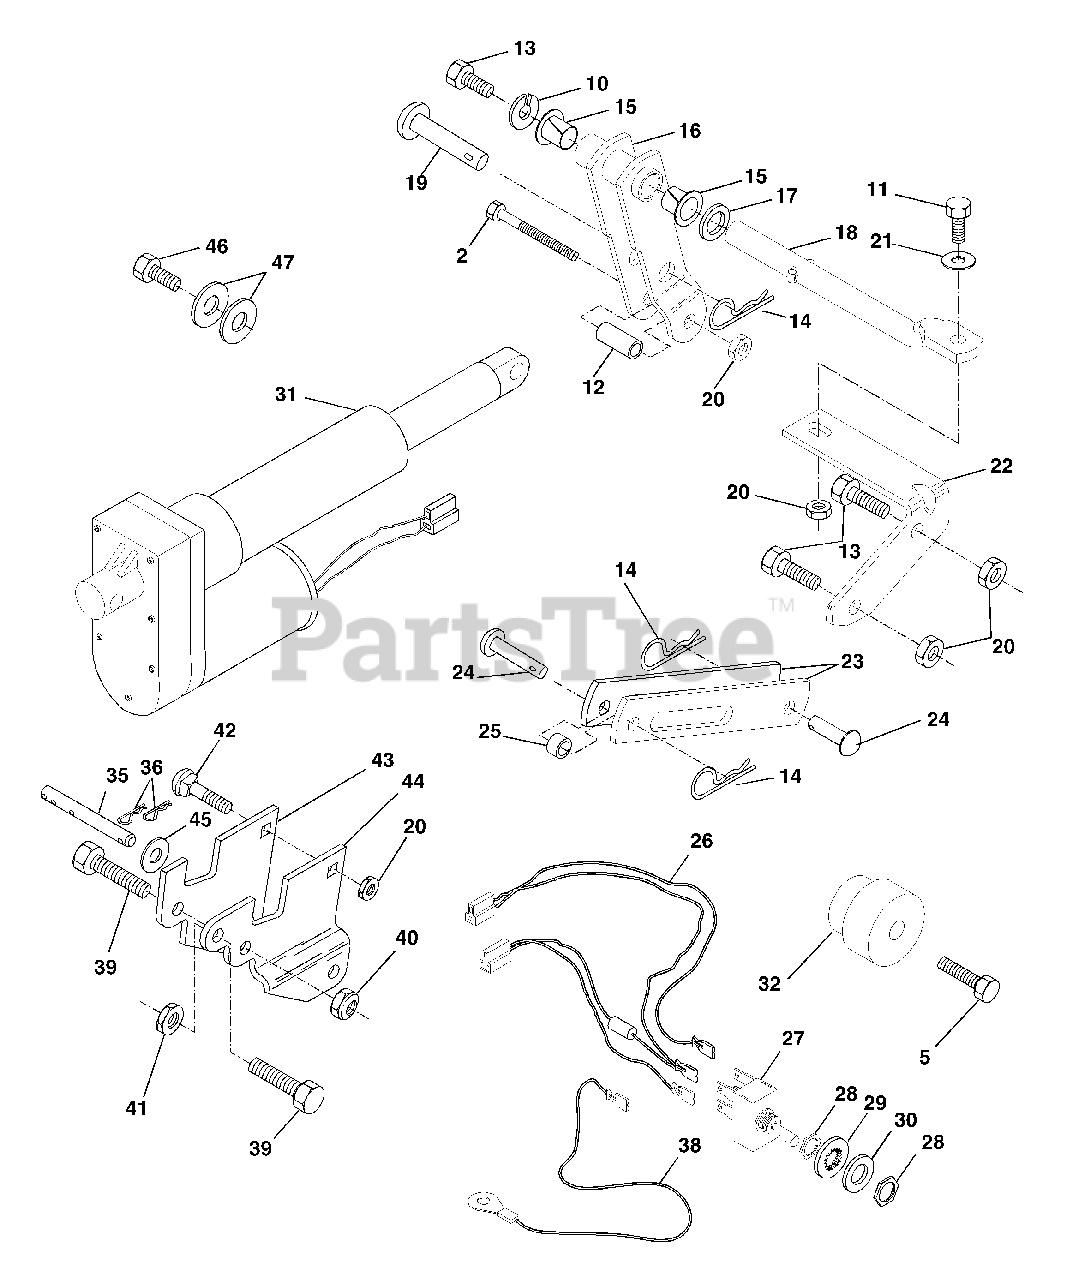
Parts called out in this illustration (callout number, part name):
2	Bolt, Hex 3/8-16 x 2-1/4 Grade 5
5	Bolt, Hex 3/8-16 x 1-3/8
10	Washer, Lock
11	Bolt, Hex 3/8-16 x 1-1/4
12	Bushing .384 x 1/2 x 1-1/4
13	Bolt, Hex 3/8-16 x 7/8
14	Spring, Retainer
15	Nyliner
16	Arm, Pivot
17	Washer 21/32 x 1 x 21 Ga.
18	Rod, Pivot Support
19	Pin, Pivot
20	Locknut 3/8-16
21	Washer 13/32 x 7/8 x 16 Ga.
22	Bracket, Pivot Rod
23	Link, Lift
24	Pin, Pivot
25	Spacer
26	Harness, Lift Kit
27	Switch, Lift
28	Nut, Switch
29	Washer, Lock Int. Tooth
30	Washer 15/32 x 3/4 x 16 Ga.
31	Electric, Actuator
32A	Hub, Lever Lift (Splined)
32B	Hub, Lever Lift (Tapered)
35	Pin, Actuator
36	Spring, Retainer
38	Wire, Ground
39	Bolt, Hex 7/16-14 x 1-1/4
40	Jam Nut 7/16-14
41	Locknut 7/16-14
42	Carraige Bolt 3/8-16 x 1-1/4
43	LH Actuator Bracket, Hydro
44	RH Actuator Bracket, Hydro
45	Washer 17/32 x 3/4 x 16 Ga.
46	Screw 5/16-18 x 1-1/4
47	Washer 11/32 x 1-1/2 x 10 Ga.
